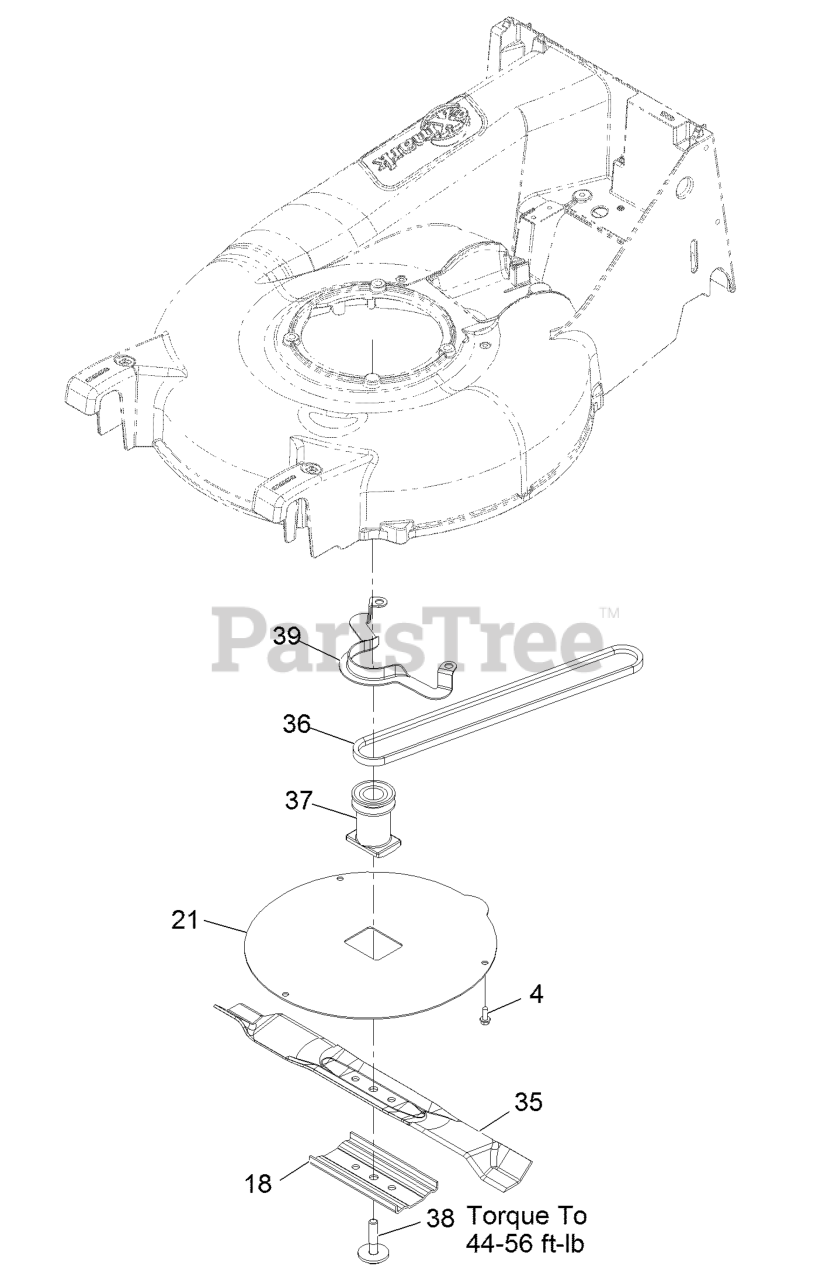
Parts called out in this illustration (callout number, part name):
4	SCREW-HWH
18	SUPPORT-BLADE
35	Blade - Medium Lift, 20.5
36	BELT,3L P21 DRIVE
37	BLADE-ADAPTER
38	BOLT-BLADE, SEM
39	GUIDE-BELT
